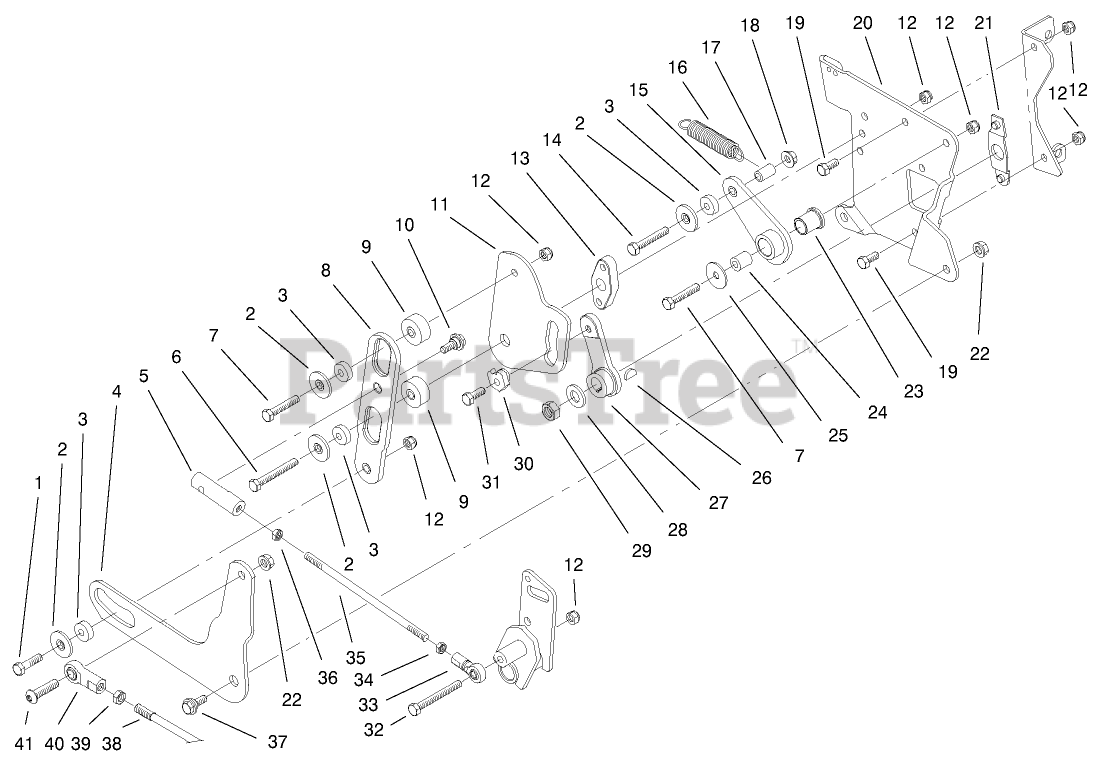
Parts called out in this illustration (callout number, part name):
1	SCREW-HH
2	RETAINER-BEARING
3	BEARING-BALL
4	SLIDER-LIFT
5	END-ROD, RH
6	SCREW-HH
7	SCREW-HH
8	SLIDER-CONTROL, SPEED
9	STANDOFF-CAM PLATE
10	BOLT-SHOULDER
11	PLATE-CAM
12	NUT-LOCK, NI
13	STANDOFF-SLIDER
14	SCREW-HH
15	ARM-RETURN TO NEUTRAL
16	SPRING-IDLER
17	STANDOFF-SPRING
18	WASHER-PLAIN
19	SCREW-HH
20	PLATE-CONTROL
21	LOCATOR-CONTROL PLATE
22	NUT-HEX
23	BUSHING-FLANGED
24	SPACER
25	WASHER-FLAT
26	KEY-WOODRUFF
27	ARM-CONTROL, SPEED
28	WASHER-FLAT
29	NUT-HEX
31	SCREW-THREAD LOCKING
32	SCREW-HH
33	END-ROD, RH
34	NUT-JAM
35	ROD-SLIDER TO PIVOT
36	NUT-JAM
37	BOLT-SHOULDER
38	ROD-LIFT
39	NUT-HJ
40	END-ROD, FEMALE
41	SCREW-HSBH
